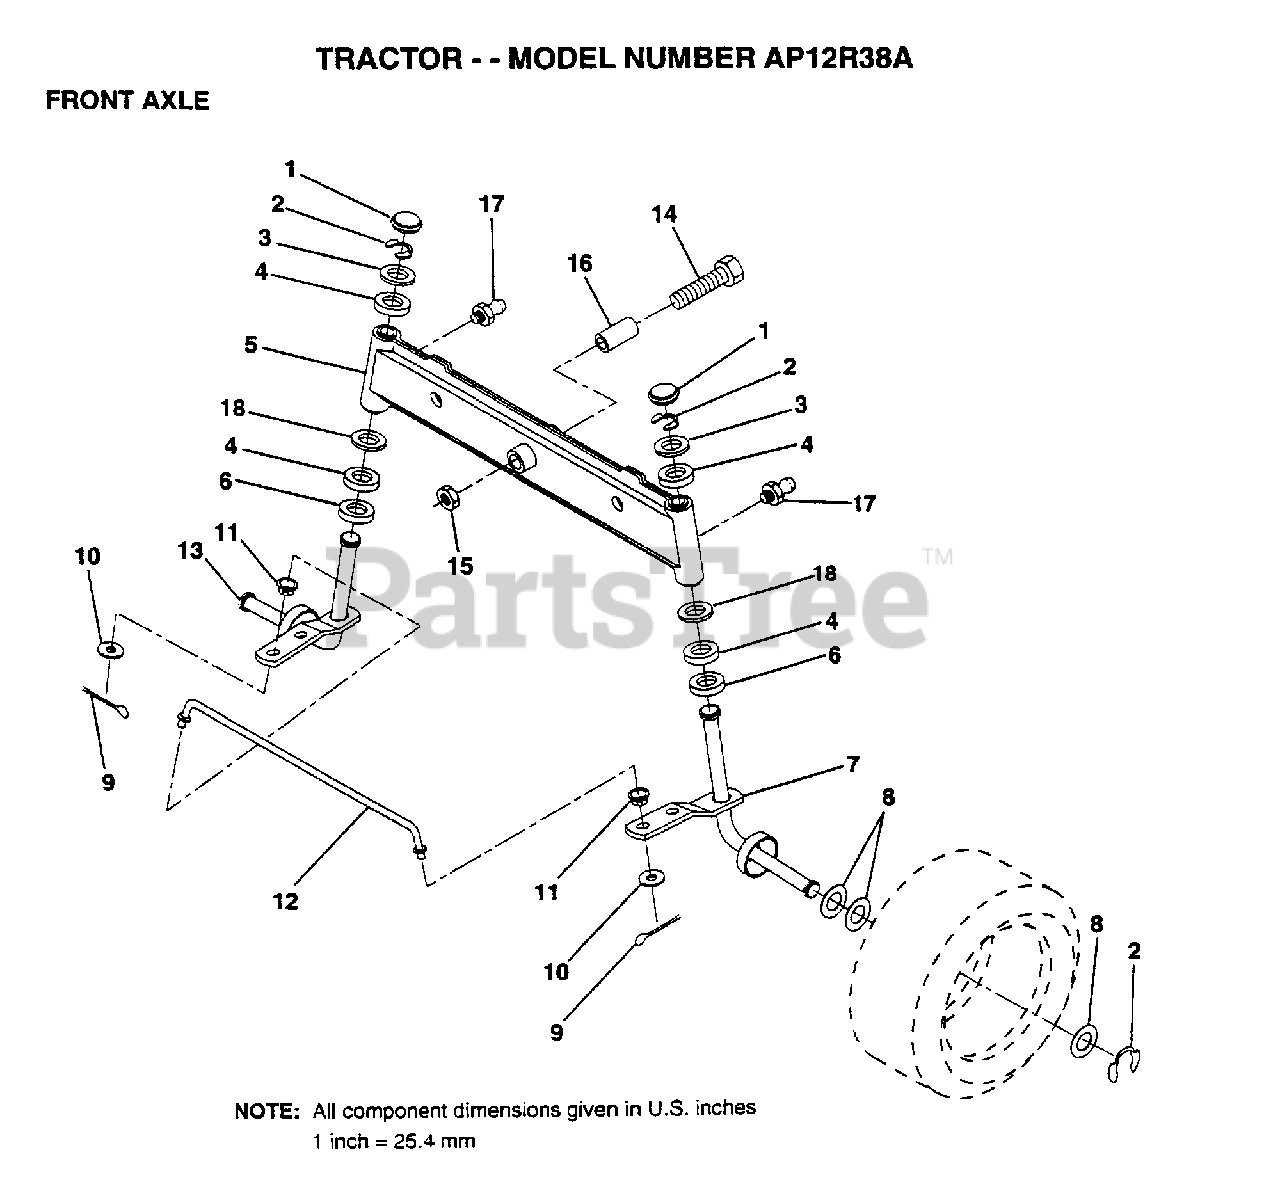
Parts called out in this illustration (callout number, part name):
1	CAP
2	RING
3	WASHER
4	COL. SRTG. BEAR.
5	AXLE ASM FRONT
6	WASHER .T
7	SPINDLE ASM RH
8	WASHER
9	COTTER PIN
10	WASHER
11	BUSHING.DRAGLINK
12	TIE ROD
13	SPINDLE ASM LH
14	BOLT HEX 5/8-11
15	"NUT-LOC,FLANGE LT"
16	BEARING
17	ZERK M
18	WASHER
